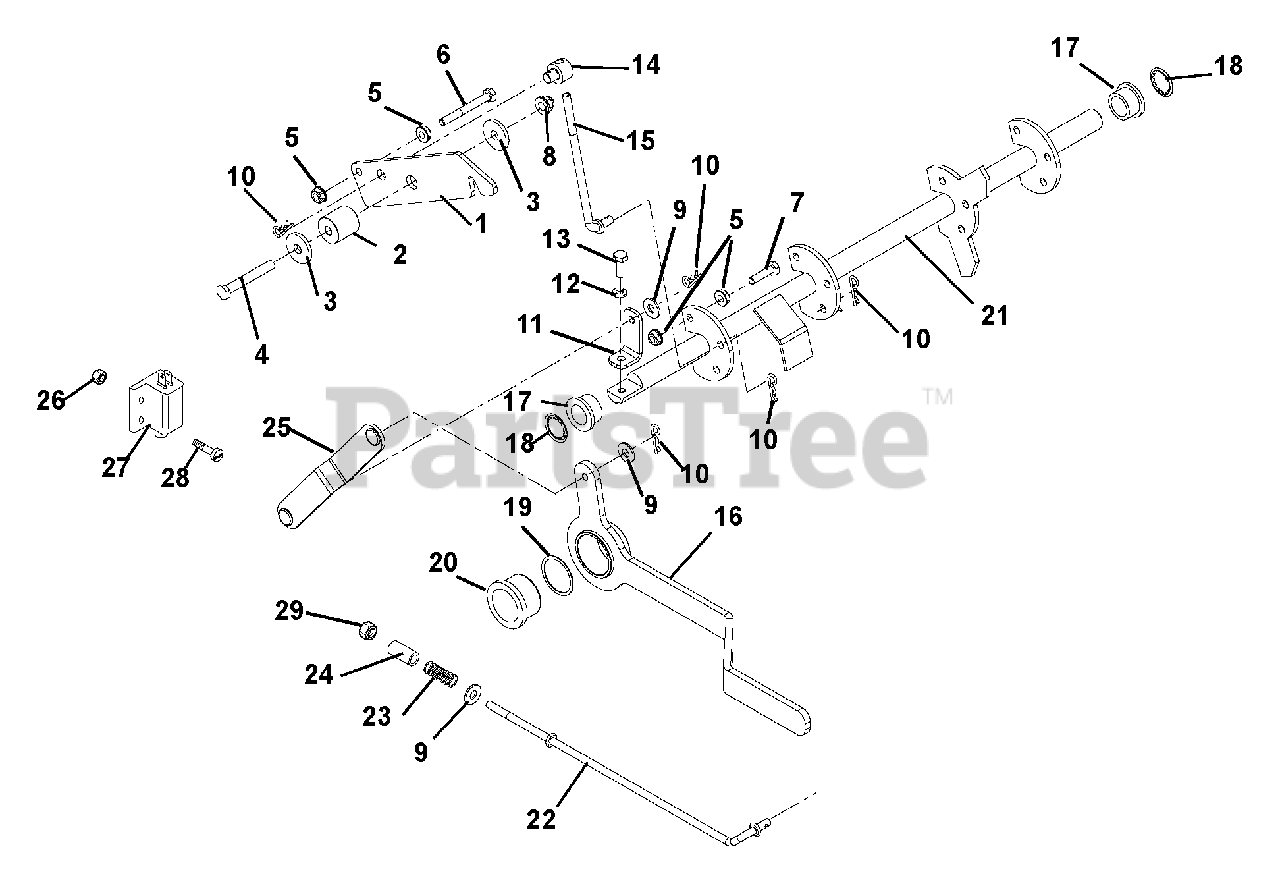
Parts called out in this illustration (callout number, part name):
1	LATCH, NEUTRAL
2	SPCR, FLG .32X.49X.192X1.00
3	WSHR-FL-STL .344X1.125X.135
4	@BLT-HEX .31-18X2.25 GR5 YWZC
5	@NUT-SPNLK-FLG .25-20 YWZC
6	@BLT-HEX .25-20X2.25 GR5 YWZC
7	@BLT-HEX .25-20X1.00 GR5 YWZC
8	@NUT-LK-NYL-FLG .31-18 YWZC
9	@WSHR-FL-STL.312X.734X.065 YWZ
10	PIN-HAIR INT .08X.18X1.18 YWZC
11	CRANK, PARKING BRAKE
12	@WSHR-LK .25X.062 REG YWZC
13	@BLT-HEX .25-20X.75 GR5 YWZC
14	TRUNNION, BRAKE .31-18 UNC
15	BRAKE LINK
16	WELDMENT, BRAKE LEVER
17	BSHG-FLG .750X1.000X.625X1.250
18	NUT, PUSH -.75" SHAFT
19	WASHER, NYLON 1.281X1.50X.03
20	BUSHING, PARKING BRAKE
21	WELDMENT, BRAKE SHAFT
22	BRAKE LINK
23	SG-COMP .045X.50X1.187
24	BSHG, SPCR .330X.500X1.01 PM
25	WELDMENT, BRAKE LINK
26	@NUT-LK-NYL 10-24 W/INSRT YWZC
27	SWITCH- DOUBLE POLE N.O./N.O.
28	@SCR-MCH 10-24X.75 HWH YWZC
29	@NUT-LK-NYL .250-20 YWZC
